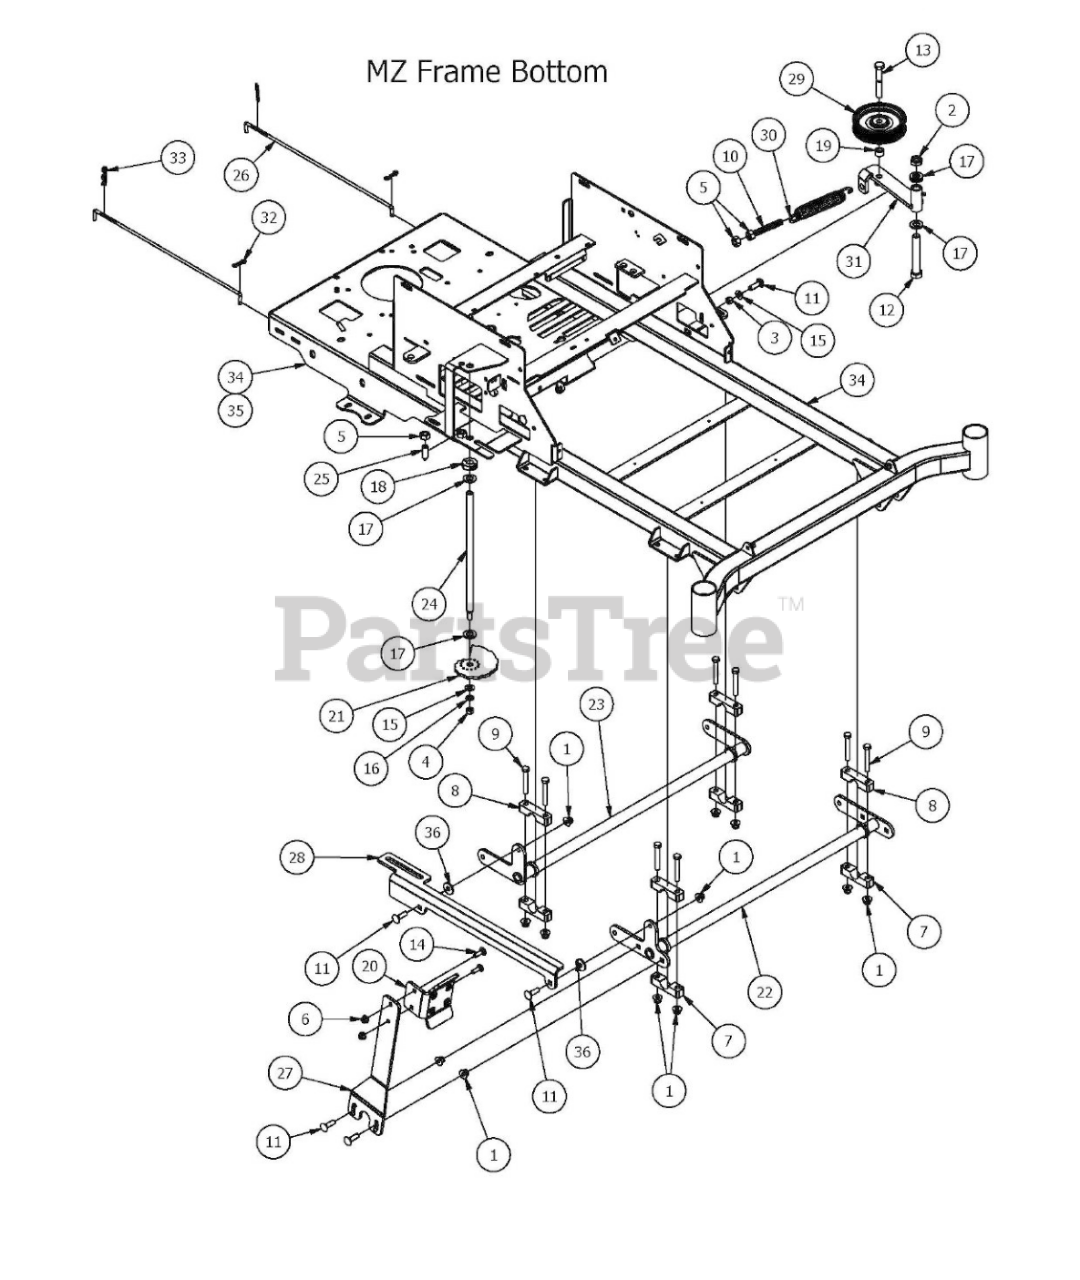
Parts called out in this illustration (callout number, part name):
1	3/8 Nylock Flange Nut
2	5/8" Nylock (1/2 Jam)
3	3/8-16 Hex Nut Zinc
4	3/8" Fine Threaded Jam Nut
5	1/2" Hex Nut
6	5/16" Nylon Flange Nut
7	Pillow Block MZ male
8	Pillow Block MZ female
9	3/8 x 2 1/2" Hex Bolt
10	All Thread-Pump Idler Tensioner
11	3/8" x 1 1/4" Carriage Bolt
12	5/8" x 4" Hex Bolt
13	1/2 x 2-3/4 Hex Bolt
14	5/16" x 1" Carriage Bolt
15	3/8" Flat Washer
16	3/8" Lock Washer
17	.630 ID Plastic Washer
18	5/8" Split Collar
19	1/2 Set Collar W/Set Screw
20	2017 MZ/ZT Shallow Foot Pedal
21	2017 MZ/ZT Cam Plate
22	Actuator Bar Front- 2017 MZ/ZT
23	Actuator Bar Rear- 2017 MZ/ZT
24	2017 Deck Height Dial Rod MZ
25	Dial Rod Plunger
26	Neutral Rod
27	2017 MZ/ZT Deck Pedal Lever
28	2017 MZ/ZT Actuator Linkage
29	4 3/4" Idler Pulley
30	2015 Deck Idler Spring
31	Pump Idler Bracket
33	Neutral Rod Clip
34	2017 MZ 42"-48" Frame
35	2017 54" Magnum Frame
36	.390 ID Plastic Washer
